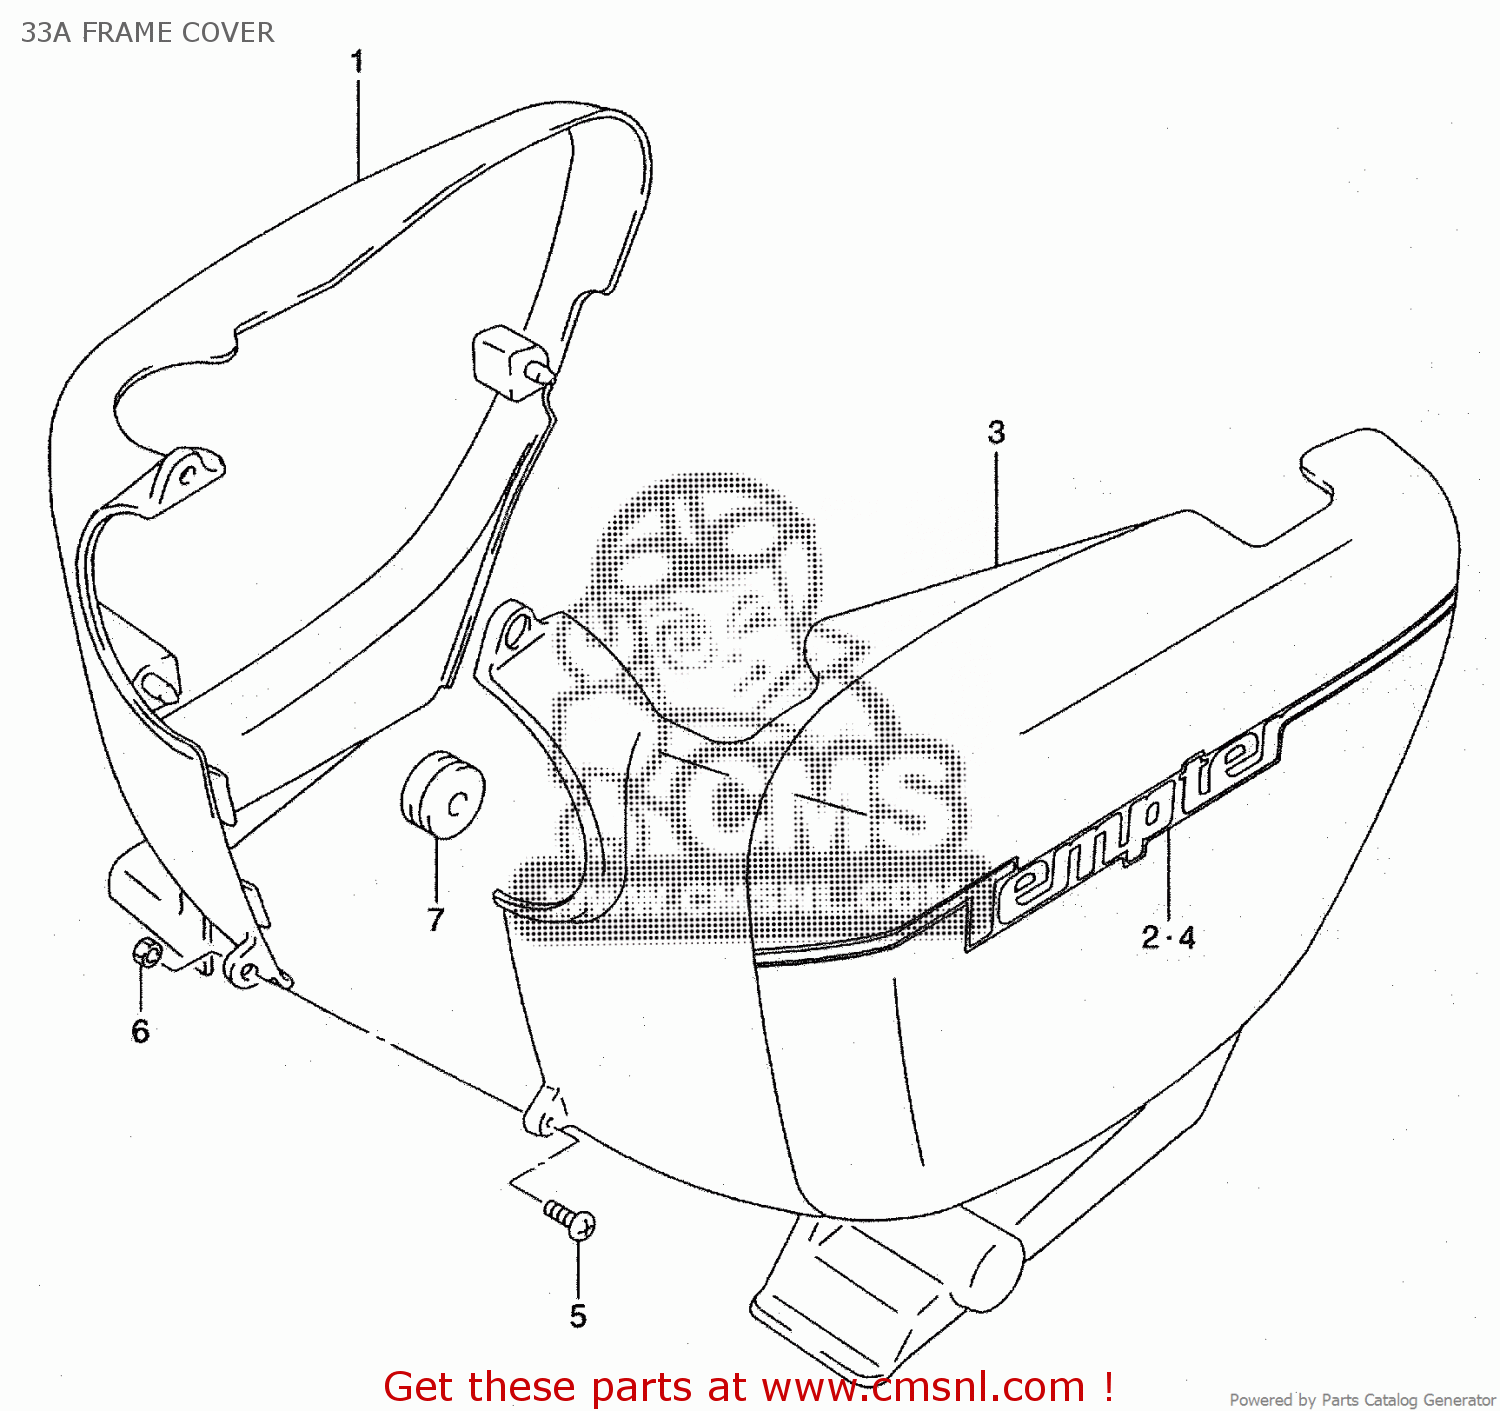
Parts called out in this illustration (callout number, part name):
5	SCREW
6	NUT
7	CUSHION
